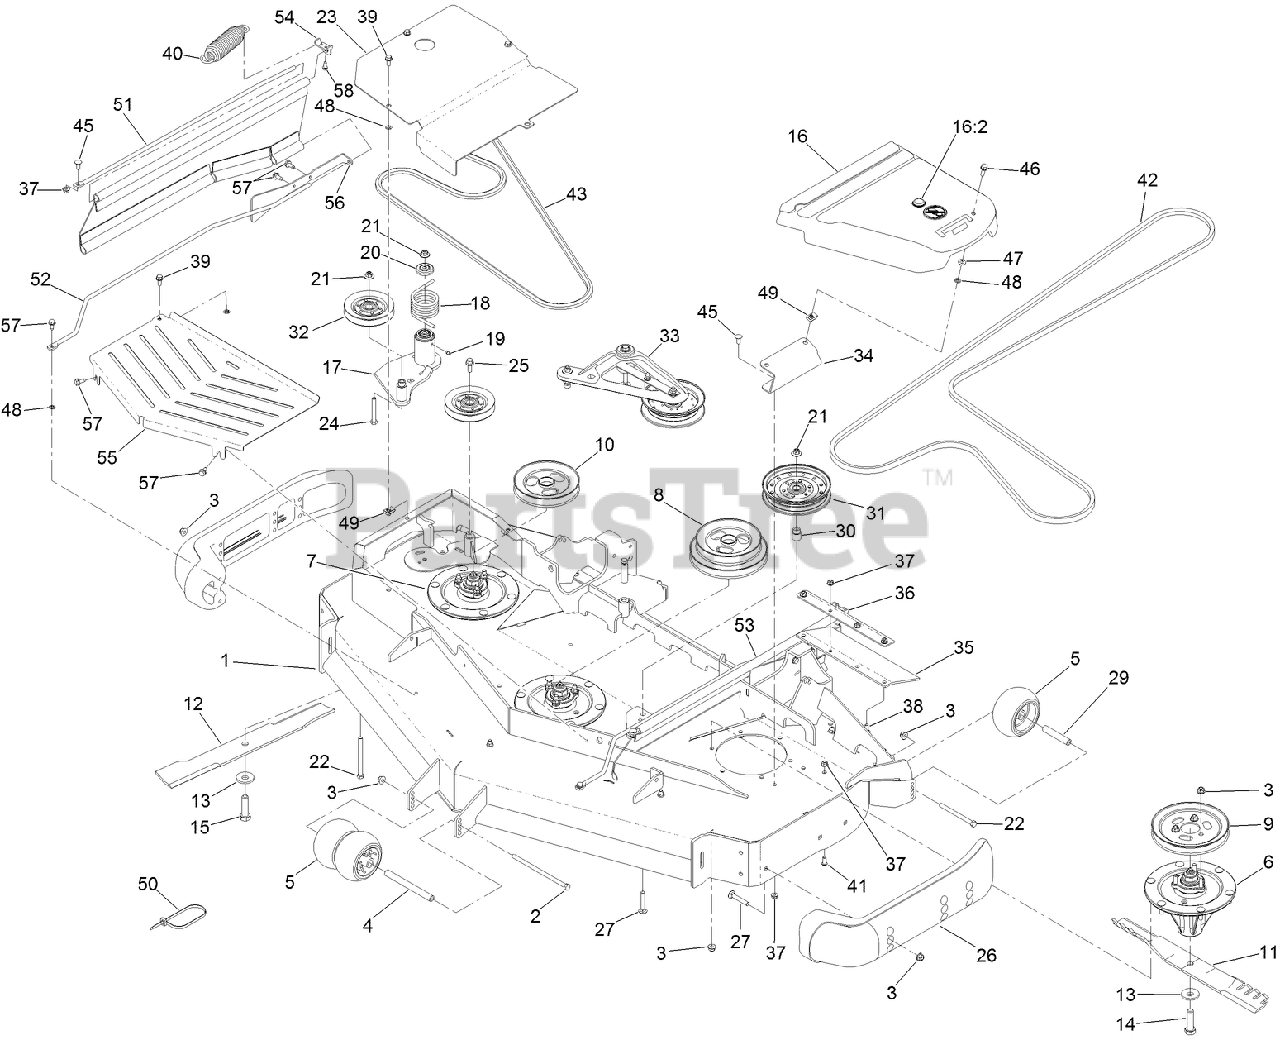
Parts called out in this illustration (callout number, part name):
1	DECK DECAL ASM
2	SCREW-HH
3	NUT-HF, NI
4	SPACER-WHEEL
5	ROLLER-SCALP, ANTI
6	SPINDLE ASM
7	LH SPINDLE ASM
8	PULLEY
9	Pulley
10	PULLEY
11	BLADE-ATOMIC, 20.5IN
12	BLADE-ROTARY, 20.5IN LOW FLOW
13	Washer-Blade Bolt, Heavy
14	SCREW-BLADE
15	SCREW-BLADE, LH
16	LH BELT COVER ASM
16:2	PLUG-PLASTIC
17	DECK IDLER ASM
18	SPRING-TORSION
19	FITTING-GREASE
20	GUARD-TOP
21	NUT-FLANGE, NI
22	SCREW-HH
23	COVER-SPINDLE
24	SCREW-HH
25	SCREW-HHF
26	SKID-BUMPER, DECK
27	SCREW-CARR
29	TUBE-SPANNER
30	Bushing, Idler
31	PULLEY-IDLER, FLAT
32	SHEAVE
33	DECK IDLER ASM
34	BRACKET-COVER, BELT
35	GUARD-TIRE
36	SUPPORT-OUTER FLAP
37	NUT-HF, NI
38	SCREW-CARR
39	SCREW-HHF
40	SPRING-EXTENSION
41	SCREW-HSBH
45	SCREW-CARR
46	SCREW-HHF
47	WASHER-THRUST
48	NUT-PUSH
49	NUT-U
50	TIE-CABLE
51	ROD-SUPPORT, UPPER
52	ROD SUPPORT, LOWER
53	GUARD SIDE
54	BRACKET-MOUNTING, UPPER
55	SHIELD-FRONT,
56	BRACKET-MOUNTING, REAR
57	SCREW-HWHTF
58	SCREW-HWH
